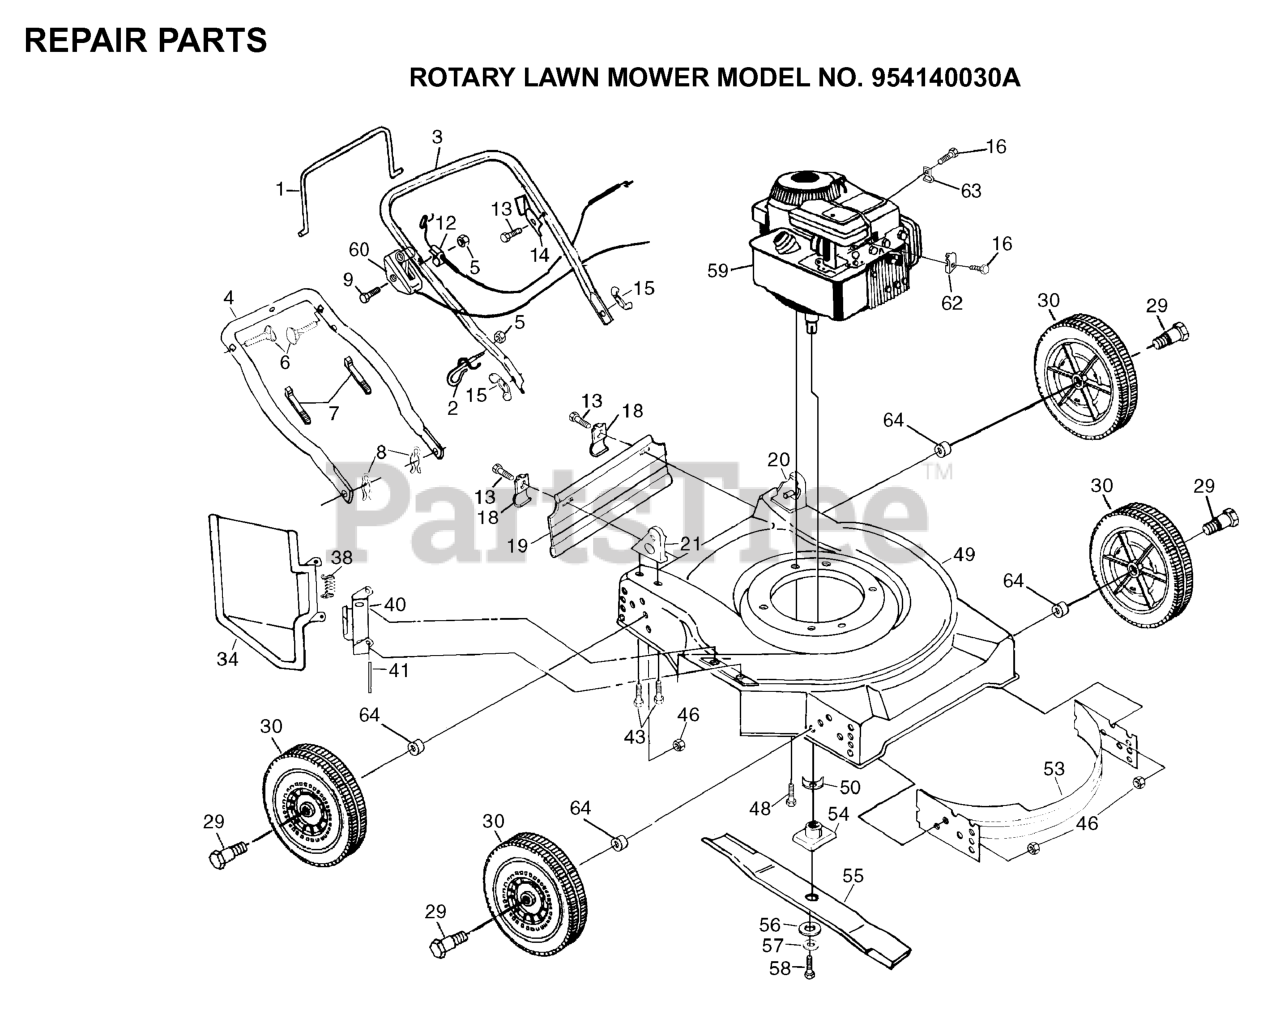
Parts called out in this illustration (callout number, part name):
1	CONTROL BAR
2	ROPE GUIDE
3	UPPER HANDLE
4	HANDLE.LOWER.STD.PNT.GREY
5	NUT
6	HANDLE BOLT
7	TIE GUIDE
8	HAIRPIN COTTER
9	SCREW 1/4-20 X 2.12
12	CABLE.MZR.51.RT.SP./PU.
13	TAPPING SCREW
14	BRACKET UPSTOP
15	NUT WING PM
16	SCREW.HEX.HEAD.WASHER.10-16
18	BRACKET DEFL PM
19	REAR SKIRT
20	HDLE BRKT ASSY LH
21	HDLE BRKT ASSY RH
30	DNO WHEEL.7.5X1.5.PR.SP.GY
38	SPRING TENSION
43	SCREW.5/16-18X3/4
46	LOCKNUT PM
48	BOLT 3/8-16X1-1/8
53	BAFFLE
54	BLADE ADAPTOR
55	BLADE.20.MULCH.(50DK,6020MD)
56	WASHER,HARDEN
57	LOCKWASHER
58	SCREW, HEX HD 3/8-24 X 1-3/8
60	THROTTLE CONTROL
63	GUIDE CLIP PM
64	SPACER.WHEEL.390.X1.0X.380.RTA
